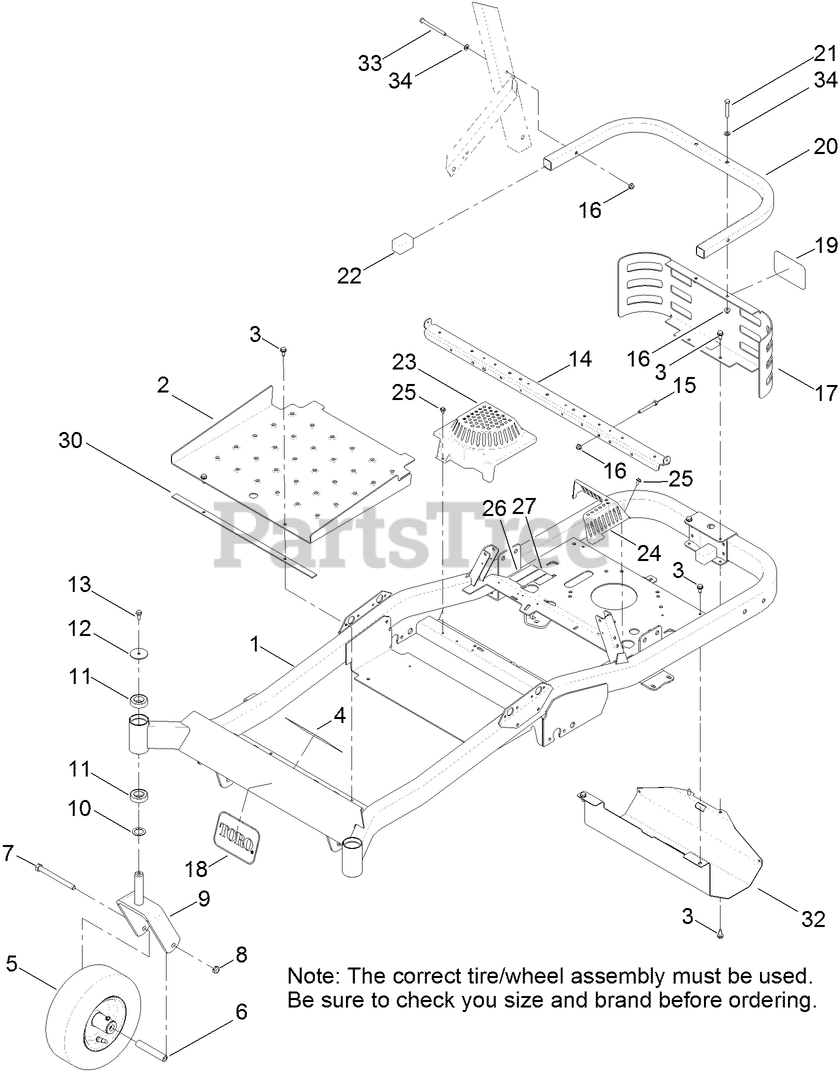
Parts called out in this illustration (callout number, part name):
2	PAN-FLOOR
3	SCREW-HWHTF
4	DECAL-SAFETY
5	TIRE AND WHEEL ASM (C S T)
5	TIRE AND WHEEL ASM (KENDA)
6	BUSHING-SPANNER
7	SCREW-HH
8	NUT-HEX
9	CASTER FORK ASM
10	WASHER-THRUST
11	BEARING-BALL
12	WASHER
13	SCREW-HHF
14	SUPPORT-SEAT
15	SCREW-HH
16	NUT-HF, NI
17	GUARD-REAR
18	DECAL
20	TUBE-GUARD
21	SCREW-HH
23	COVER-FAN, RH
24	COVER-FAN, LH
25	SCREW-HHFTF
26	DECAL-SERIAL
27	DECAL-EMISSIONS, E P A
30	STRIP-VIBRATION, ANTI
33	SCREW-HH
34	WASHER-PLAIN
